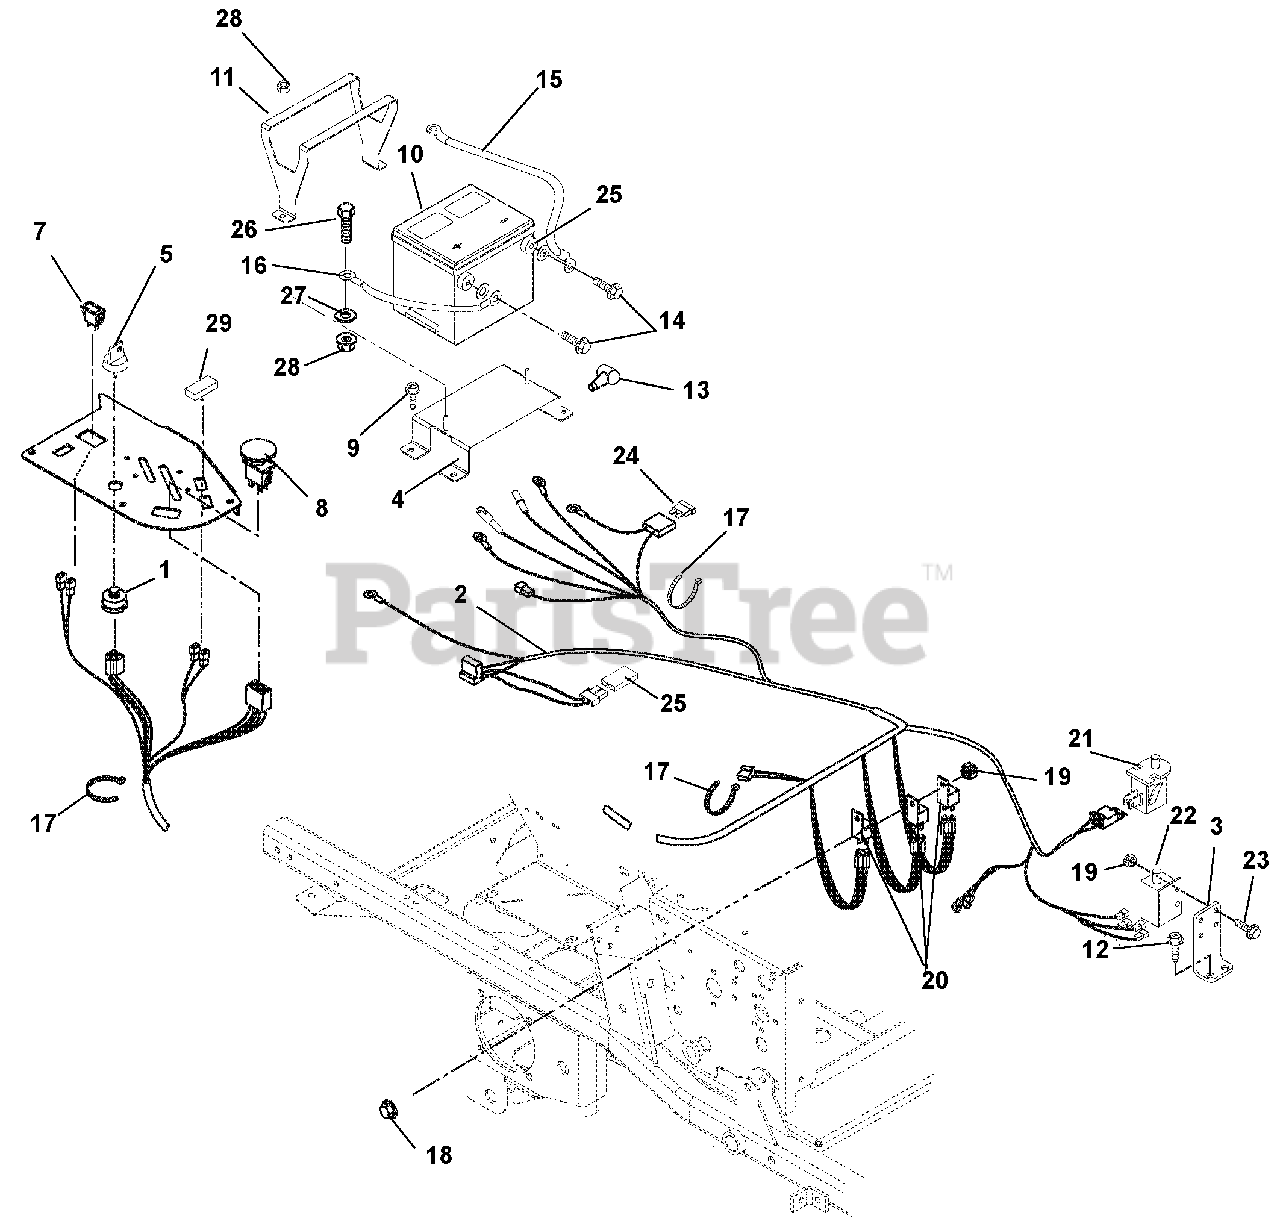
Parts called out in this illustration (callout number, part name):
1	Switch, Ignition
2	Harness, Vertical A/C, Wire PM200
3	Mount, Safety Switch
4	Weldment, Battery Support
5	Key, with Shield
6	Ignition Key Set
7	Hour Meter
8	Switch, PTO Clutch
9	Screw, Tapping .38-16 x .75 Hex Washer Head
11	Bracket, Battery Hold-Down
12	Screw, Tapping .25-20 x .50 Hex Washer Head
13	Battery Terminal Boot, Red
14	Bolt, Hex .25-20 x .75 Grade 5
15	Cable, Starter 18.O Red
16	Cable, Ground 18.0 Black
17	Cable Tie
18	Screw-Machine 10-24 x .50 Hex Washer Head
19	Nut, Locking Nylon 10-24 With Insert
20	Relay (Included with Harness)
21	Switch, Snap Mounting
22	Switch, Double Pole N.O./N.O.
23	Screw, Machine 10-24 x .75 Hex Washer Head
24	Fuse, 20 Amp
24	Fuse, 15 Amp
24	Fuse, 10 Amp
25	Diode, Connector Shell
26	Bolt, Hex .31-18 x .75 Grade 5
27	Washer, Flat Steel .344 x .688 x .065
28	Nut, Locking Top Flange .31-18
29	Light, Indicator
